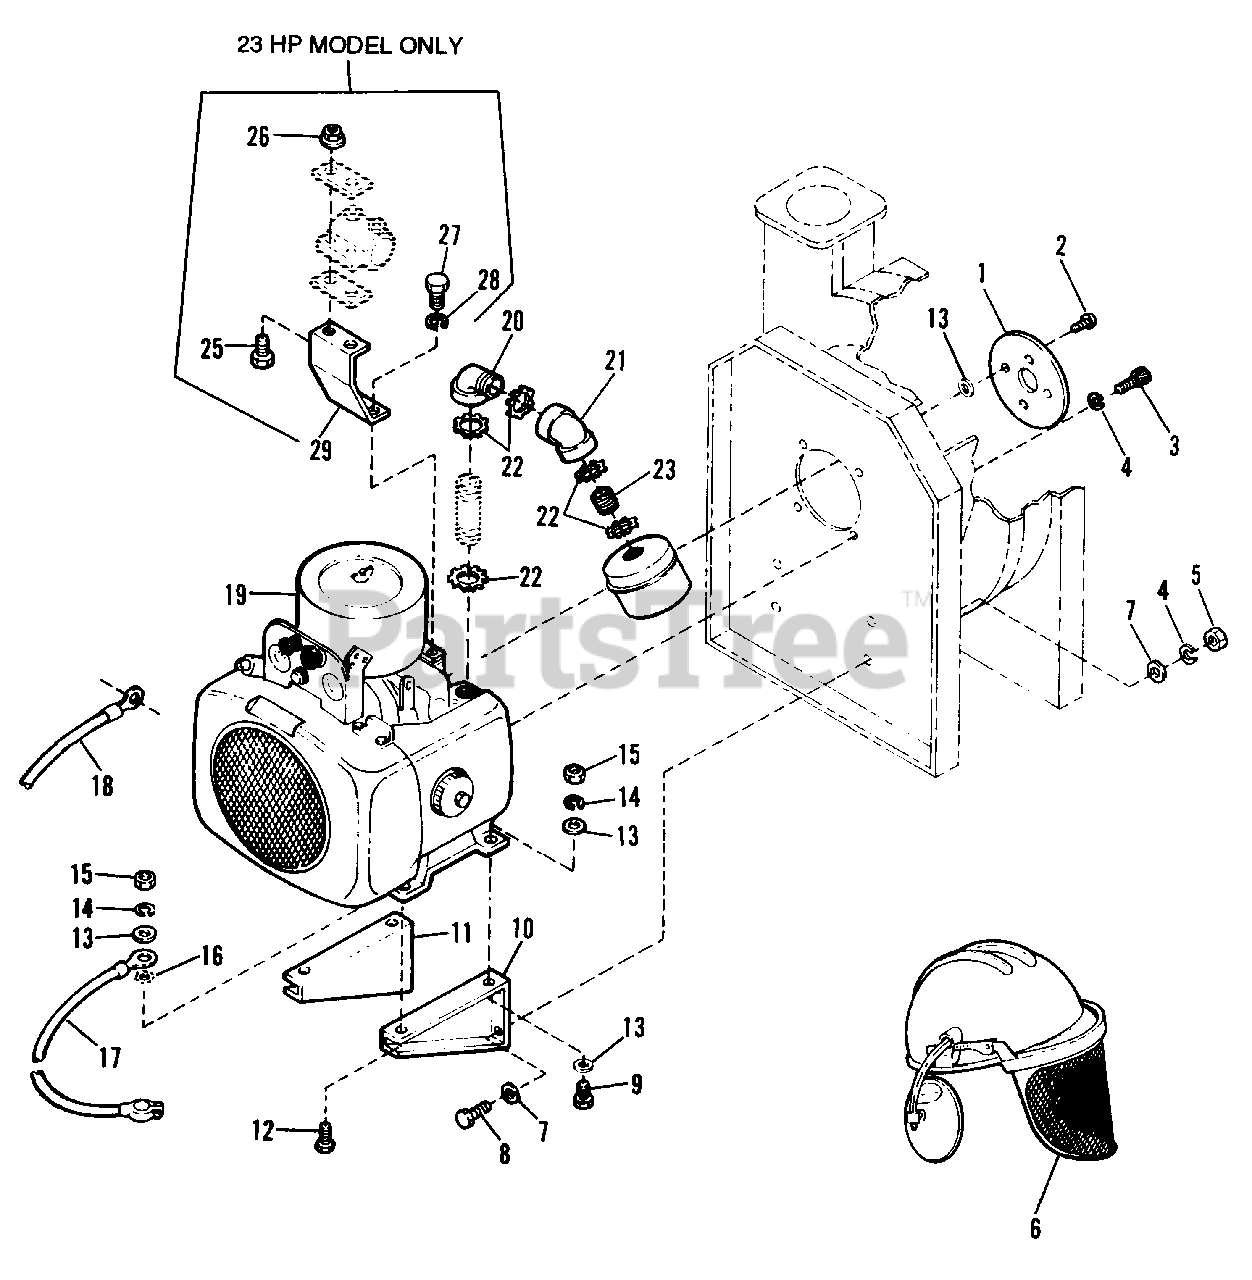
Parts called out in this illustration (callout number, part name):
1	GUARD, Seal (23 HP)
1	GUARD, Seal (20 HP)
2	SCREW, Button Hd. (Qty. 2 on 23 HP model)
3	CAPSCREW, Hex Hd., 7/16-14 x 1
4	LOCKWASHER, 7/16
5	NUT, Hex, 7/16-14
6	HARDHAT, Logger's
7	WASHER, 7/16
8	CAPSCREW, 7/16-14 x 1-1/4
9	CAPSCREW, 3/8-16 x 1-1/4 (20 HP model)
10	BRACKET, Engine Mounting, R.H.
11	BRACKET, Engine Mourning, L H.
12	CAPSCREW, 3/8-16 x 1-1/2 (Qty. 4 on 23 HP model)
13	WASHER, 3/8 (Qty.10 on 23 HP model)
14	LOCKWASHER, 3/8
15	NUT, Hex, 3/8-16 (Qty. 4 on 23 HP model)
16	LOCKWASHER, E x ternal Tooth, 3/8
17	CABLE, Battery, 30", Black
18	CABLE, Battery, 17", Red (20 HP Negative)
18	CABLE, Battery, 41", Red (23 HP Negative)
19	ENGINE, Kohler
20	ELBOW, Street 1", 90ø
21	ELBOW, 1", 45ø
22	LOCKNUT, Conduit, 1" (Qty. 10 on 23 HP model)
23	NIPPLE, 1 x 1-1/2
25	CAPSCREW, 1/4-20 x 1-1/2
26	NUT, Flange, 1/4-20
27	CAPSCREW, 1/4-20 x 1/2
28	LOCKWASHER, 1/4
29	BRACKET, Standoff
